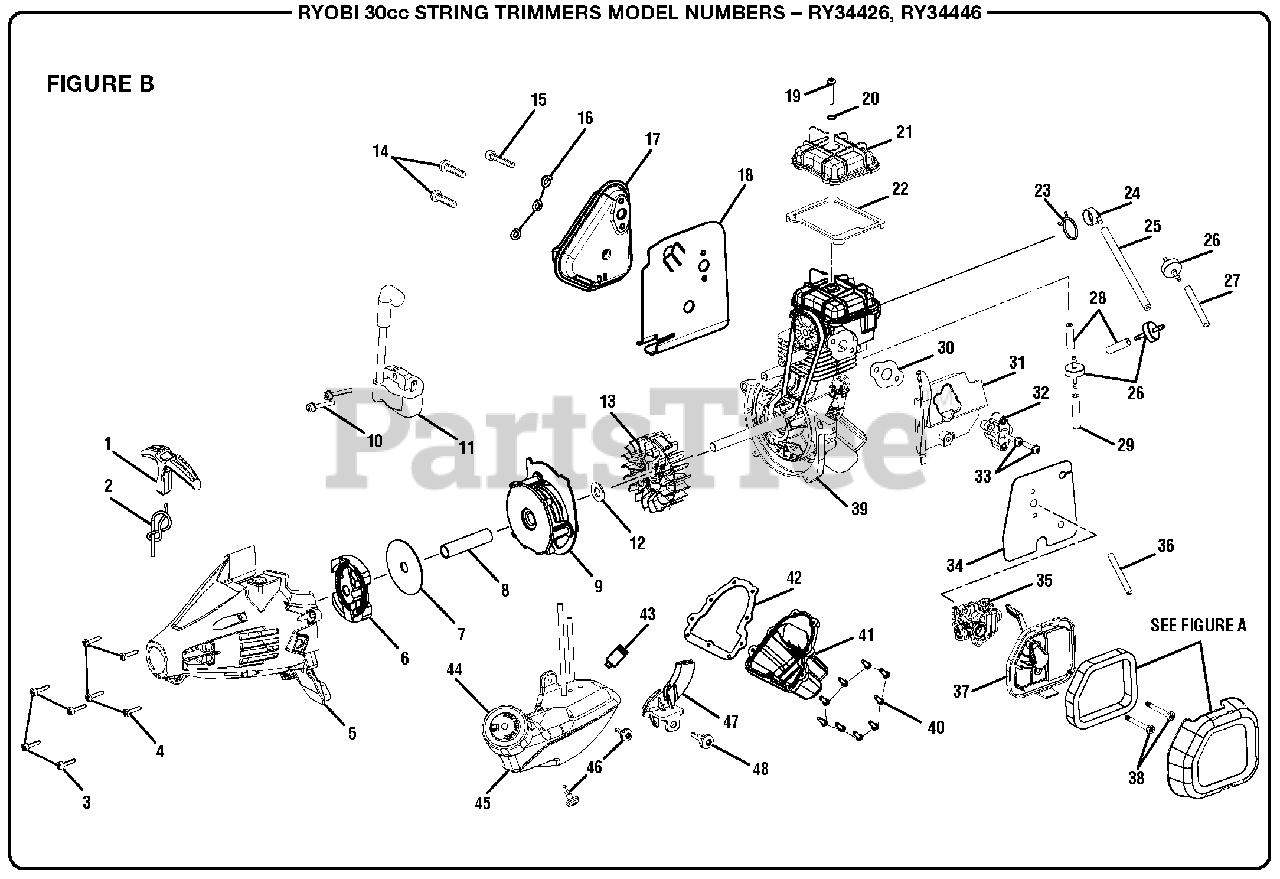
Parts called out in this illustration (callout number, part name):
1	Starter Grip
2	Starter Rope
3	Screw (M4 x 18 mm, T20 Torx Soc. Hd.)
4	Screw (M4 x 16 mm, T20 Torx Soc. Hd.)
5	Starter Housing Assembly
6	Clutch Assembly
7	Washer (ID9.63 x OD50.75 x 1.10t)
9	Starter Housing Assembly
10	Screw (M4 x 19 mm, T20 Torx Pan Hd.)
11	Ignition Module
12	Washer (ID9.75 x OD20 x 1.6t)
13	Flywheel Assembly
14	Screw (M5 x 38 mm, T25 Torx Truss Hd.)
15	Cap Screw (M5 x 50 mm, T25 Torx Soc. Hd.)
16	Lock Washer (ID5.1 x OD9 x 1.3t)
17	Muffler Assembly
18	Muffler Gasket
19	Screw (M4 x 27 mm, T20 Torx Truss Hd.)
21	Cam Cover
22	Cam Cover Gasket
23	Wire Clamp
24	Breather Fitting
25	Breather Hose (120 mm)
26	Check Valve
27	Shield Sleeve (M6 x 50 mm)
28	Breather Hose (24 mm)
29	Breather Hose (34 mm, Crankcase)
30	Heat Dam Gasket
31	Air Baffle
33	Screw (M5 x 23 mm, T25 Torx Pan Hd.)
34	Heat Shield w/Gasket (Carburetor)
35	Carburetor
36	Breather Hose (50 mm)
37	Air Box Base
38	Screw (M5 x 44 mm, T20 Torx Hd.)
39	Short Block Assembly
40	Screw (M4 x 12 mm, T20 Torx Hd.)
42	Oil Pan Gasket
43	Fuel Filter
45	Fuel Tank w/Cap
46	Shoulder Screw (M4 x 14 mm, T25 Torx Truss Hd.)
47	Throttle Cable Guide
48	Shoulder Screw (M4 x 19 mm, T25 Torx Truss Hd.)
